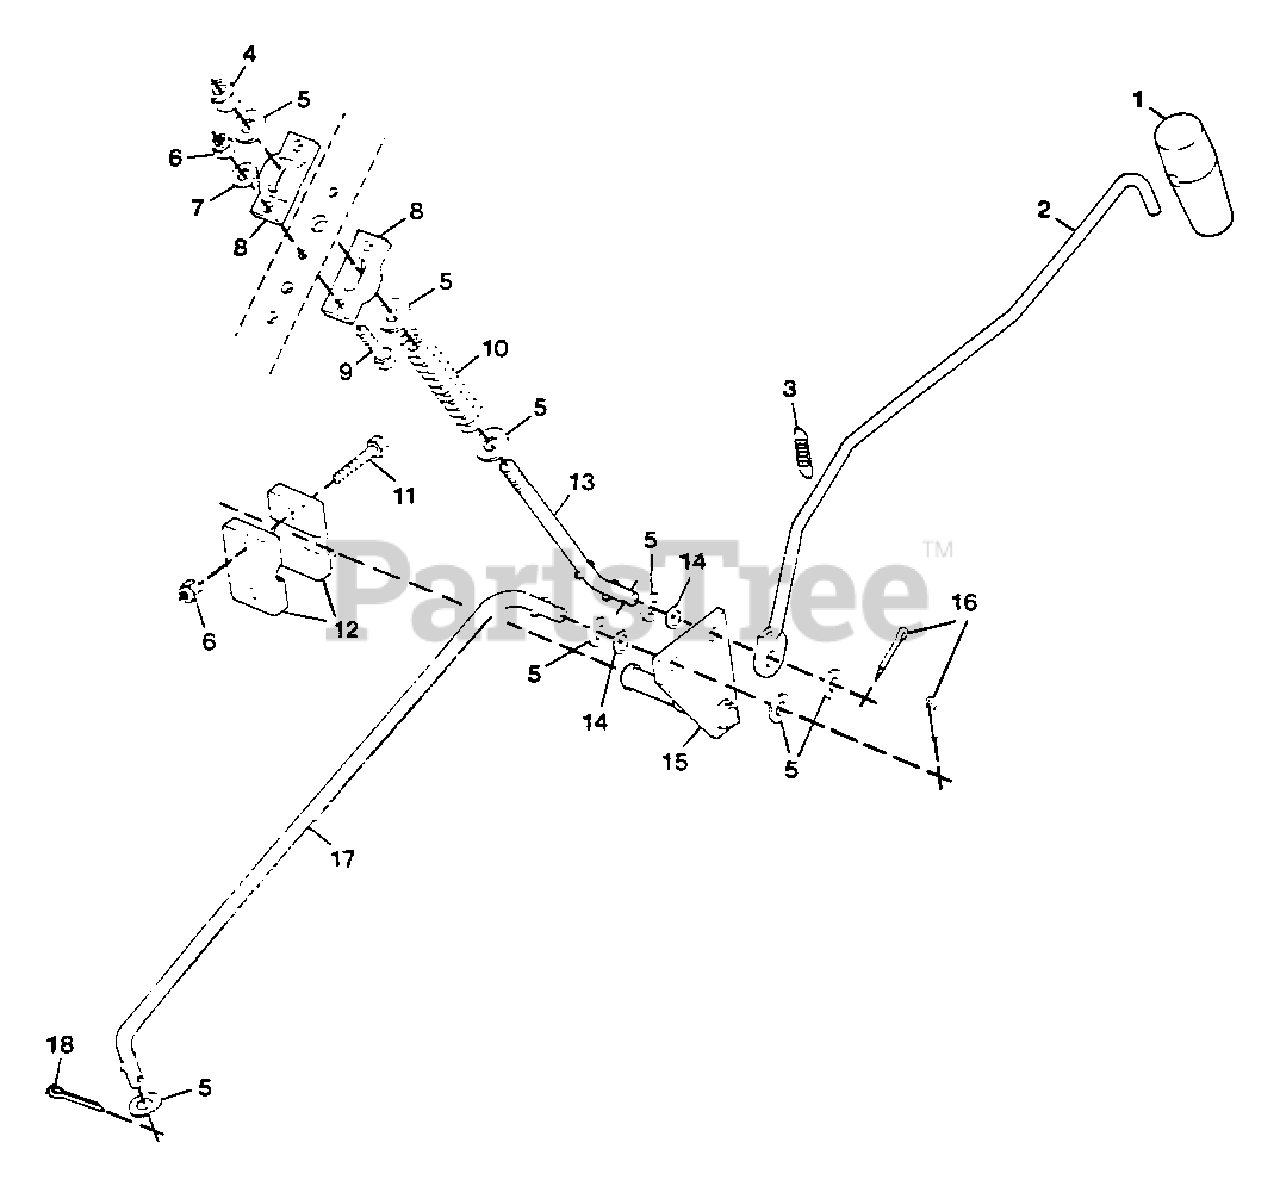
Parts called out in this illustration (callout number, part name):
1	Handle, Rubber Shifter
2	Rod, Shifter
3	Spring, Extension .50x1.25
4	Nut, Lock 3/8-16
5	Washer, Flat .406x.812x.065
6	Nut, Lock 1/4-20
7	Washer, Flat .281x.625x.065
8	Cam, Shifter
9	Bolt. Hex 1/4-20x1.00
10	Spring, Comp. .720x2.75
11	Bolt, Hex 1/4-20x1.50
12	Block, Shift Lever
13	Link, Shifter Stop
14	Washer, Spring .375 I.D.
15	Weldment, PTO Bellcrank
16	Pin, Cotter .125x.750
17	Link, PTO Control
18	Pin, Cotter .09x.75
